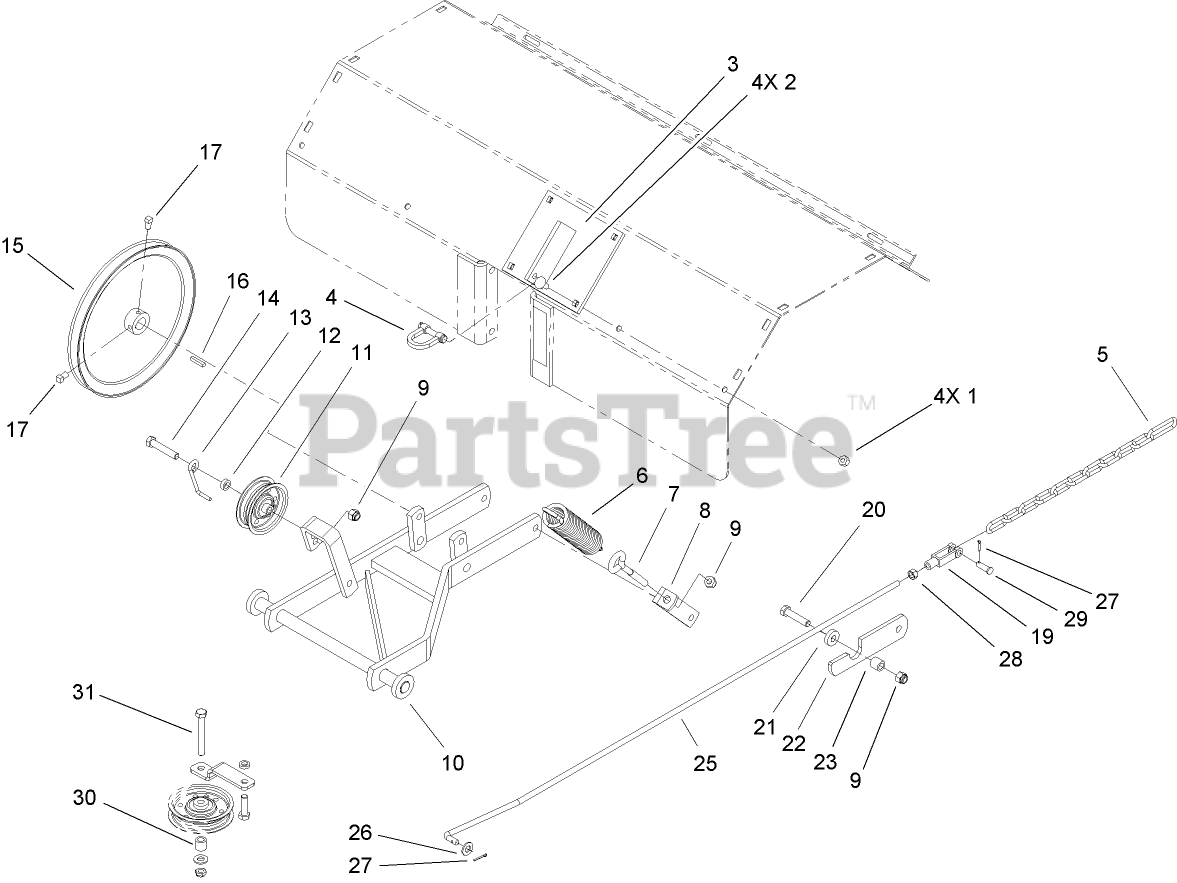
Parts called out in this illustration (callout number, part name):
1	NUT-LOCK, NI
2	BOLT-CARR
4	CLEVIS ASM
5	CHAIN-LIFT
6	SPRING
7	EYEBOLT
8	BRACKET-SPRING
9	NUT-LOCK, NI
10	HITCH ASM
11	PULLEY-IDLER
12	SPACER
13	GUIDE-BELT
14	SCREW-HH
15	PULLEY
17	SCREW-SQH
19	YOKE-ADJUSTABLE
20	SCREW-HH
22	CATCH-SPRING
23	SPACER
25	ROD-LIFT
26	WASHER-FLAT
27	PIN-COTTER
28	NUT-HEX
29	PIN-CLEVIS
30	SPACER
31	SCREW-HH
